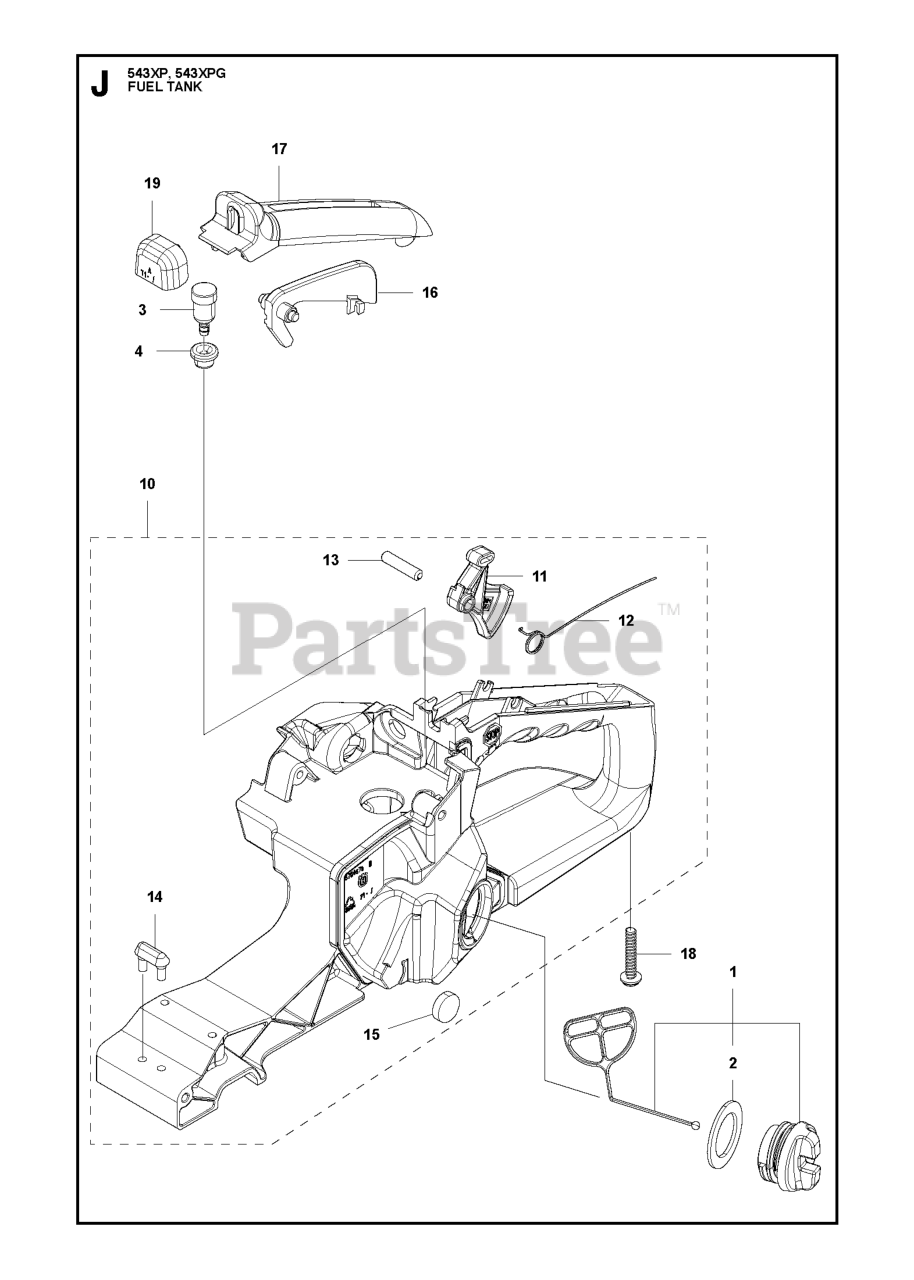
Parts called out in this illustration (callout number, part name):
1	TANK CAP ASSY
4	GROMMET
10	HANDLE ASSY
11	THROTTLE LEVER
13	SPRING PIN
15	HELPER(M) Z285033370
17	COVER GRIP
